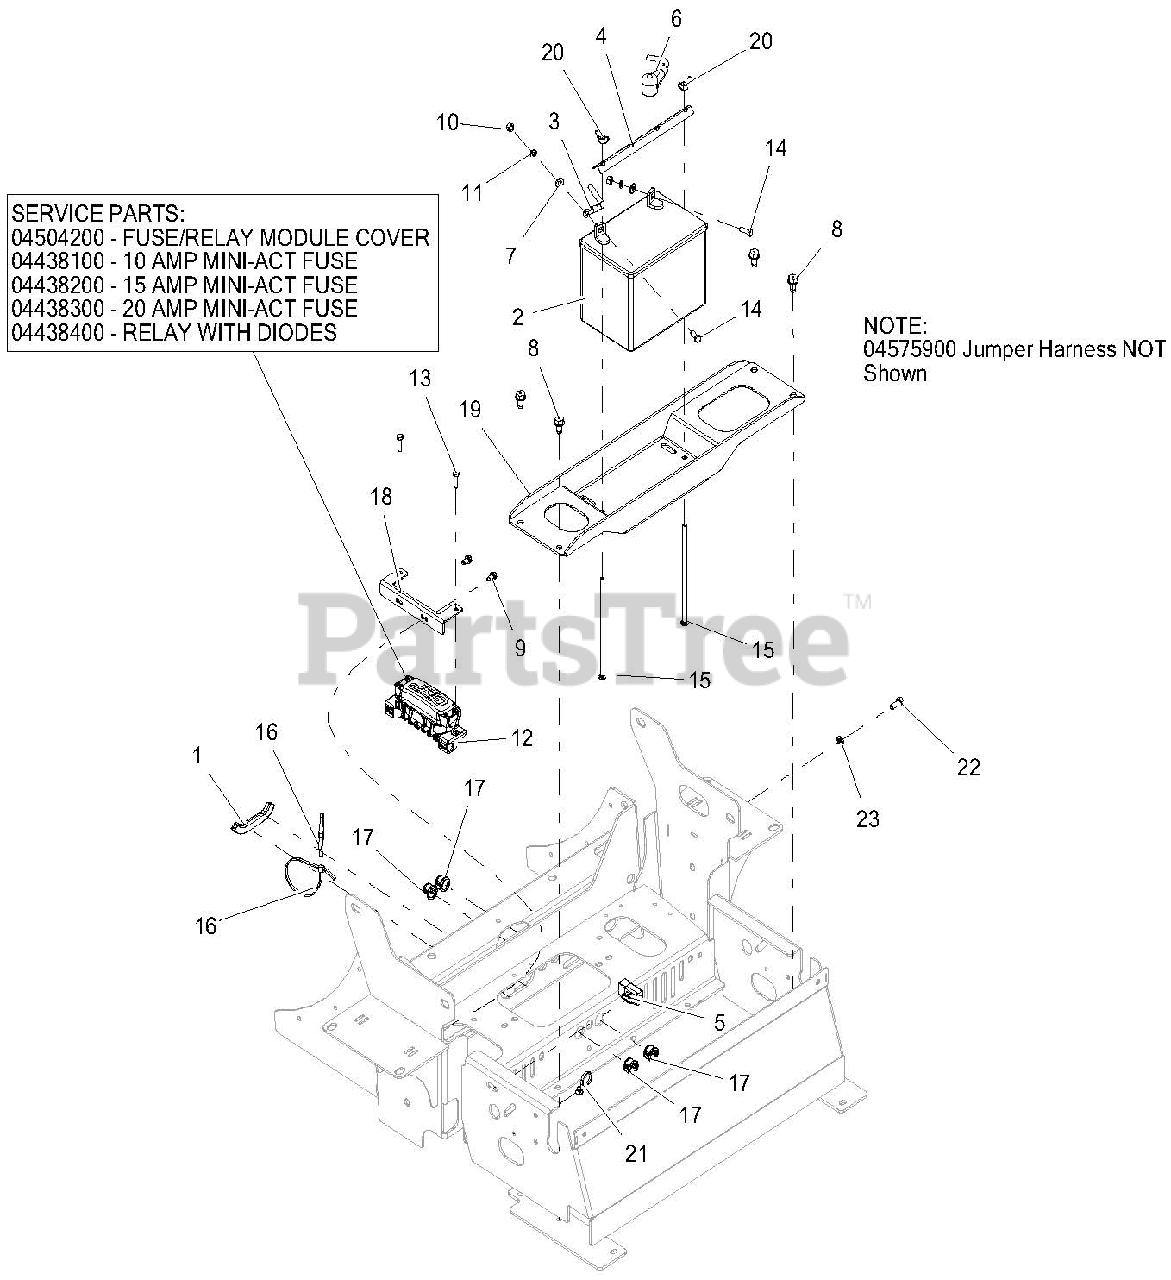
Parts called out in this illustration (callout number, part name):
1	STRIP, COWL - 1.50 LG
2	BATTERY, 300 CCA 10U1L
3	CABLE, NEGATIVE BATTERY 35.00"
4	HOLD DOWN - BLK
5	SWITCH, SNAP IN -N.O./N.O
6	CABLE, POS BATT W/ BOOTS 6 X 35
7	WSHR-FL-STL.281X.62X.065 YWZC
8	SCR-TAP .38-16X.75 HWH TR YWZ
9	SCR-TAP .25-20X.50 HWH TR YWZ
10	NUT-HEX .25-20 YWZC
11	WSHR-LK .25X.062 REG YWZC
12	HARNESS, PT400 GAS WIRE
13	@BLT-HEX M6-1.0X25 YWZC
14	BLT-HEX .25-20X.75 GR5 YWZC
15	BLT-RDHDSQNK .25-20X7.50 G2 YWZC
16	CABLE, TIE 5.50 LG
17	BUSH, PANEL SNAP .687X.875X.56
18	BRKT, FUSE HOLDER MOUNTING-RED
19	TRAY, BATTERY-RED
20	NUT-LOCKING WING 1/4-20
21	CABLE TIE W/ TREE
22	@BLT-HEX M8-1.25X20 YWZC
23	WSHR-LK .31X.078 REG YWZC
